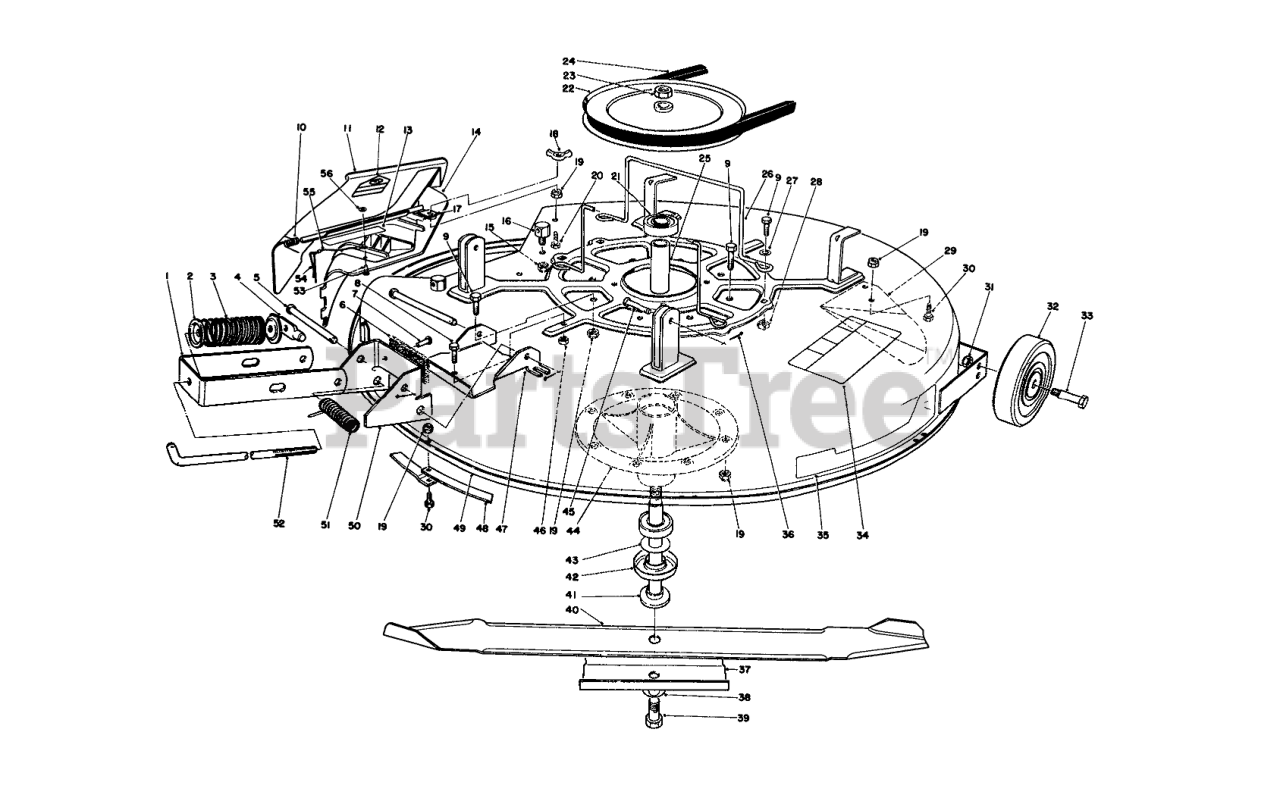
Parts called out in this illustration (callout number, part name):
1	Bracket-Engagement
2	RETAINER-SPR. TOP
3	SPRING-COMPRESSION
4	SHAFT-DECK ADJ.
5	PIN-CLEVIS
6	PAD-BRAKE
7	RIVET .187 X 7/16 BRASS
8	SCREW-HH
9	SCREW-HH
10	SPRING
11	Deflector (Incl. Ref. #12)
12	DECAL-DANGER
13	DECAL-DANGER, DEFLECTOR
14	Assy.-Cover, Discharge (Incl. Ref. #53-56)
15	NUT-LOCK, SIDE
16	POST-PIVOT
17	Brace-Cover, Rear
18	NUT-WING
19	NUT-LOCK, NI
20	SCREW-HH
21	BEARING-BALL
22	PULLEY
23	NUT-HEX
24	V-BELT, DECK
25	SPACER-BEARING
26	GUIDE-BELT
27	WASHER-PLAIN
28	216 Washer
29	Kicker
30	SCREW-HH
31	NUT-LOCK, NI
32	WHEEL-DECK
33	BOLT-WHEEL
34	DECAL-DANGER, THROWN OBJECT
35	DECAL/RECYCLER 32" BACK
36	PIN-COTTER
37	STIFFENER
38	WASHER-BELLEVILLE
39	SCREW-HH
40	BLADE-RECYCLER
41	SHAFT-SPINDLE
42	SHIELD-BEARING
43	SPACER-HARDNED
44	SPINDLE
45	PIN-CLEVIS
46	NUT-HEX
47	Plate-Deck, Brake Mtg.
48	RING-DECK
49	Deck-Cutting
50	Brake (Incl. Ref. #6-7)
51	SPRING
52	ROD-ENGAGEMENT
53	RIVET-BLIND
54	PIN-LOCKING, CHUTE
55	LANYARD
56	WASHER-PLAIN
